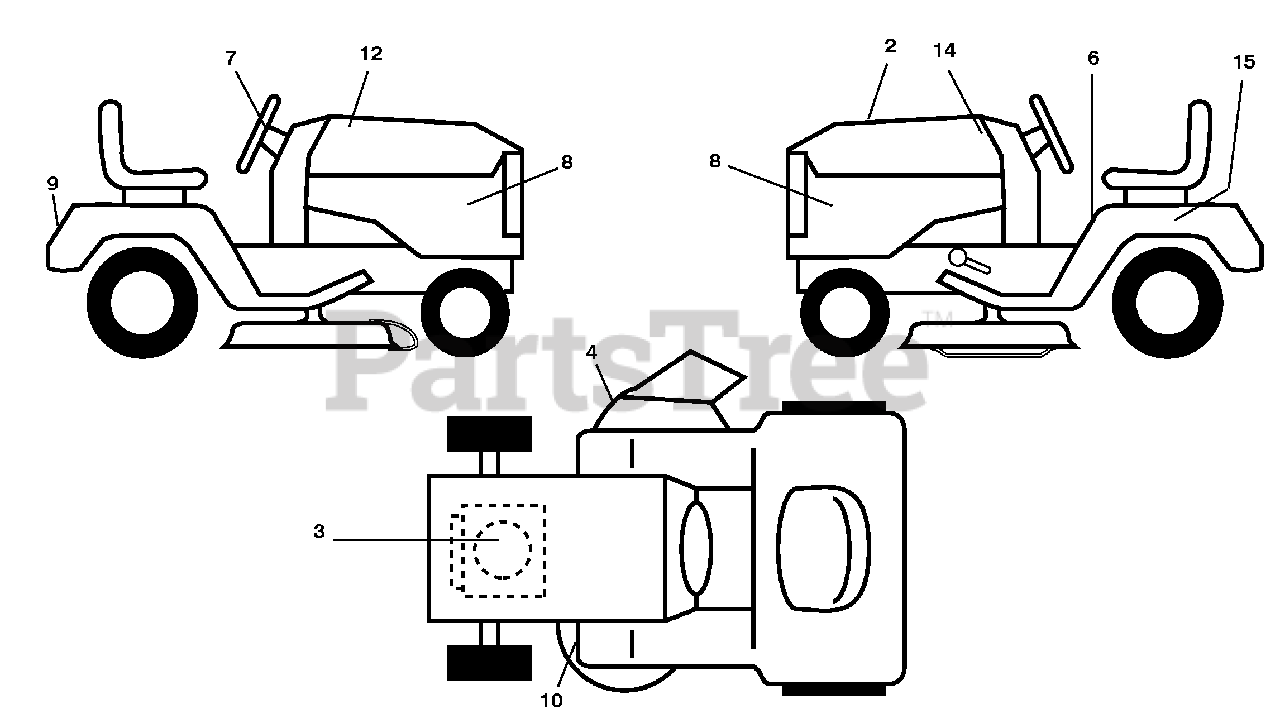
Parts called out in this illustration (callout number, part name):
2	Decal, Replacement
3	Decal, Engine HP
4	Decal, Warning
6	Decal, Fender Danger English/French
7	Decal, Ins Str Wh
8	Decal, Side Panel
9	Decal, Fender
10	Decal, V-Belt Sch.
12	Decal, Hood RH
14	Decal, Hood LH
15	Decal, Caution, Battery
15	Decal, Handle Lft Height Adj.
15	Decal Bypass
15	Manual, Operator's (E&F)
15	Manual, Parts (E&F)
